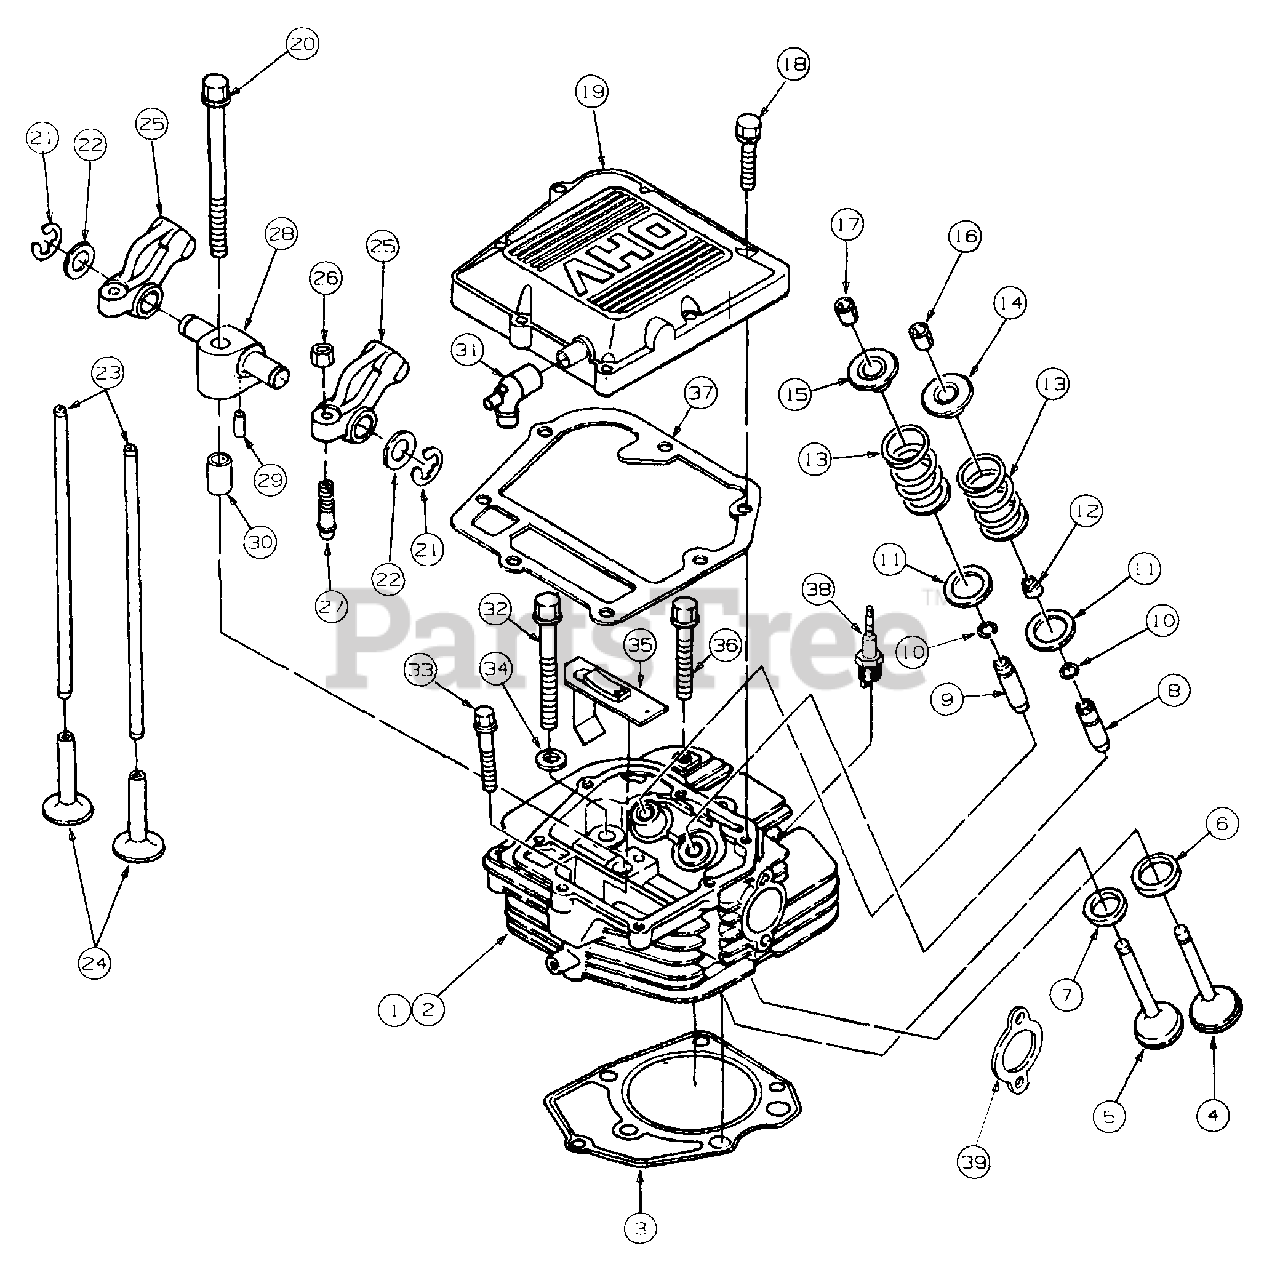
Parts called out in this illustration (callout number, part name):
1	Head Assy, Cylinder
2	Head, Cylinder
3	Gasket, Cylinder Head
4	Valve, Intake
5	Valve, Exhaust
6	Seat, Intake Valve
7	Seat, Exhaust Valve
8	Guide, Intake Valve
9	Guide, Exhaust Valve
10	Ring, Valve Guide
11	Washer, Valve Spring
12	Seal, Intake Valve Stem
13	Spring, Valve
14	Retainer, Intake Valve Spring
15	Retainer, Exhaust Valve Spring
16	Lock, Intake Valve
17	Lock, Exhaust Valve
18	Screw, Hex Flange M6 x 1 x 25 mm
20	Bolt, Cylinder Head M10 x 1.5 x 125 mm
21	Clip, Retainer
22	Washer, Rocker Arm
25	Arm Assy, Rocker
26	Nut, Lash Adjusting
27	Screw, Lash Adjusting
28	Shaft, Rocker Arm
30	Pin, Hollow Dowel
31	Connector, Breather Tube
32	Bolt, Cylinder Head M10 x 1.5 x 86 mm
33	Bolt, Cylinder Head M8 x 1.25 x 50 mm
34	Washer, Flat, M10
36	Bolt, Cylinder Head M10 x 1.5 x 66 mm
37	Gasket, Valve Cover
38	Plug, Spark
39	Gasket, Exhaust
